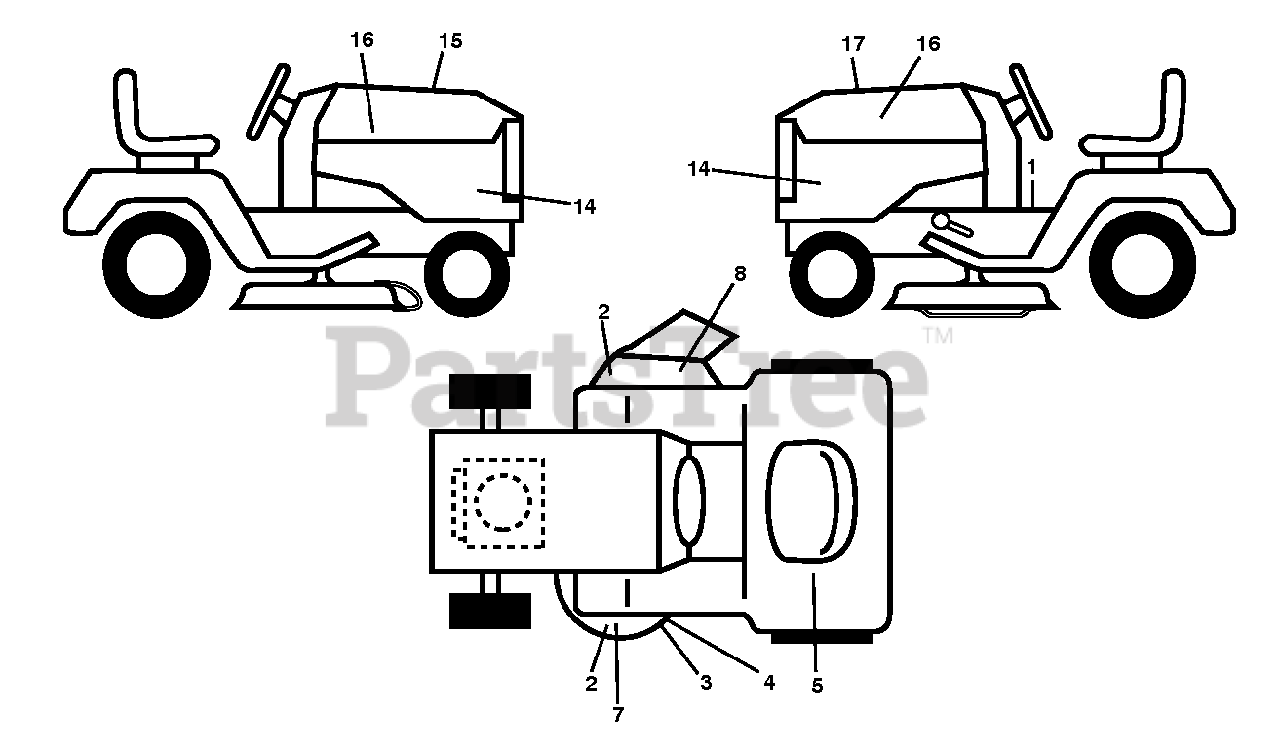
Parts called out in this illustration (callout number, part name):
1	DECAL.FENDER.WARNING.ENGLISH
2	DECAL.DECK.CLEARCUT.NOSTEP
3	DECAL.MOWER.SCH.48/54.PREM
4	Deck Decal, WA
5	DECAL.RESERVEFUELSELCTR.ENG
7	Deck Decal, 48"
8	DECAL.TRACT/ZTR.DECKWARN.HUSQ
14	Tractor Side Panel Decal
15	DECAL.WARNING.CUST.RESP.E85.
16	DECAL.BADGE.170MM.TEXTLOGO.
17	DECAL RPL K66.48F.KOH KT7.TGB
